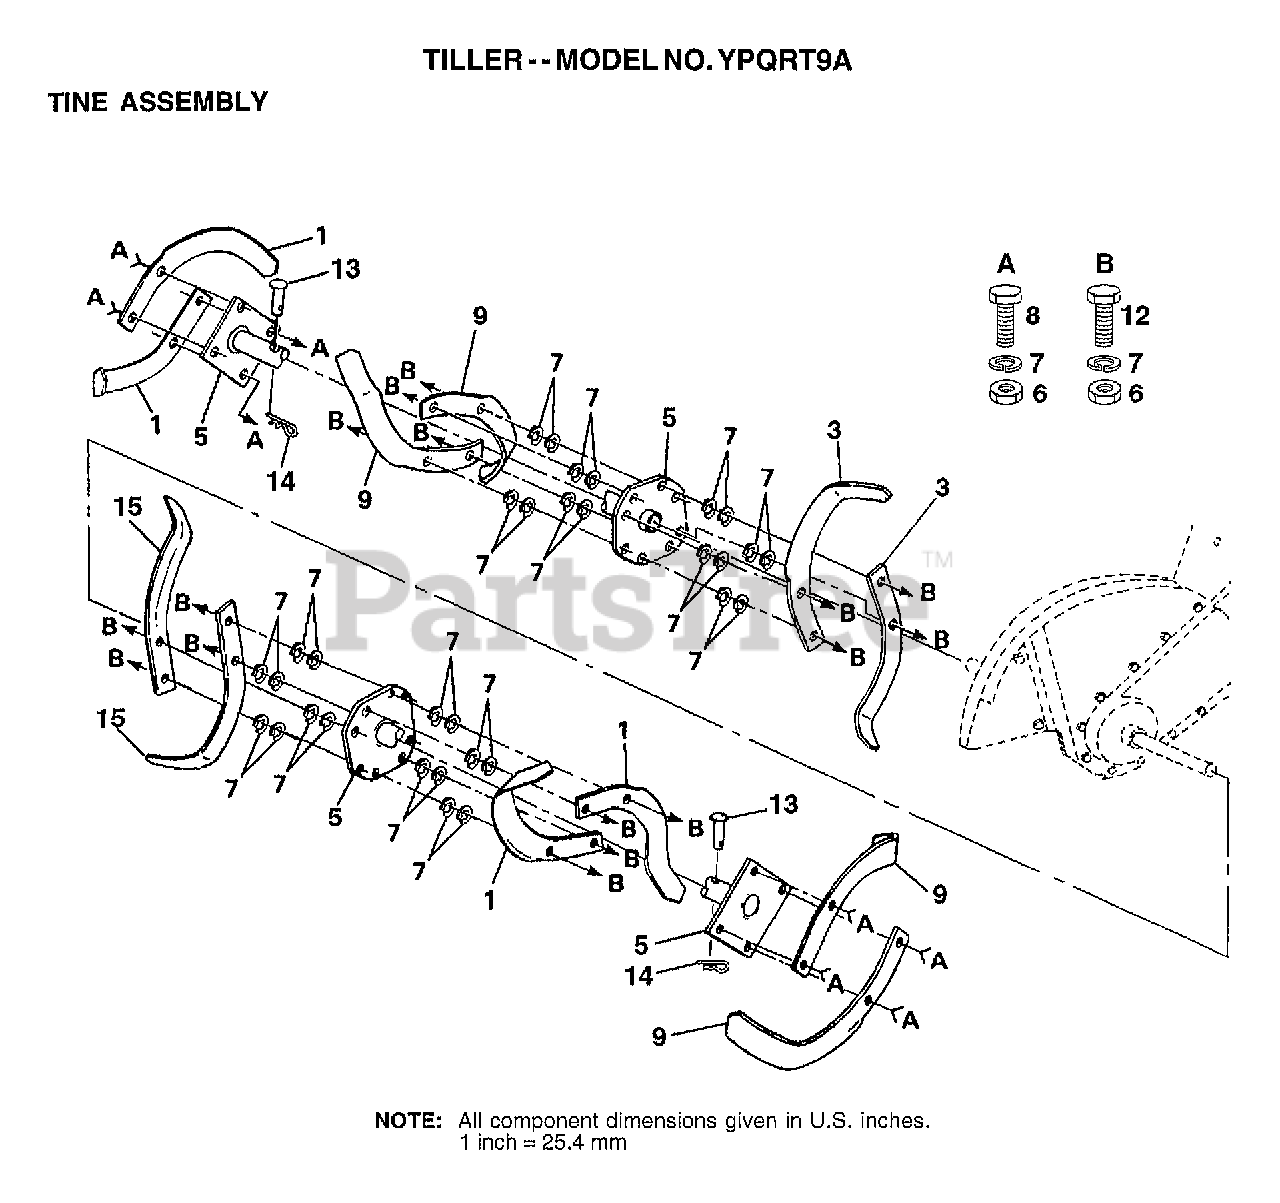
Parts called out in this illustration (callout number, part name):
3	TINE.LH.CRT
5	TINE ASSY CRT
7	LOCKWASHER
8	BOLT
12	BOLT.3/8-24X1-1/2
13	RIVET.PAN HD.1.75
14	RETAINER.SPRING
15	TINE RH CRT
